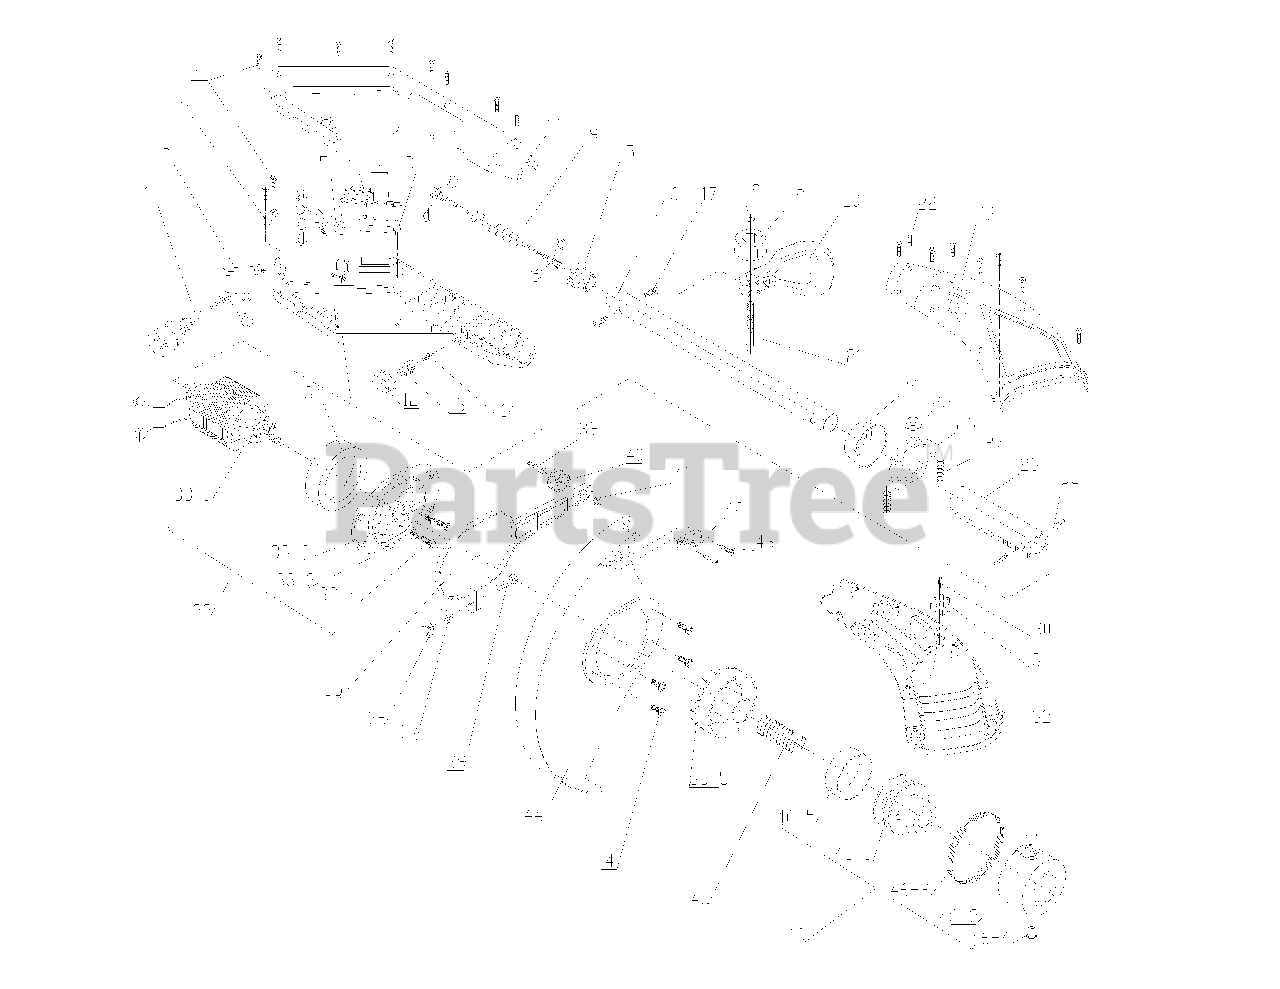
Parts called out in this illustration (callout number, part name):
1	POWER CORD
2	CORD GUARD
3	PLATE (PRESSING CORD)
10	UPPER HANDGRIP (R)
11	UPPER HANDGRIP (L)
15	JOINT PIPE
16	CENTRAL TUBE
20	CENTRAL HANDGRIP
23	HOUSING (R)
26	FIXED RING
28	EXPANDING RING
31	TERMINAL BLOCK
32	HOUSING (L)
33	MOTOR ASS'Y
33-2	FIXED PLATE
33-5	CUTTER ASS'Y
34	CUSHION RING
35	EGDER GUIDE
39	SHAFT PIN
42	WIRE CUTTING BLADE
46	SPOOL CARRIER ASS'Y
46-1	SPOOL CARRIER
46-2	WIRE-CUTTING
46-3	SPOOL COVER
46-5	BLISTER PACK
